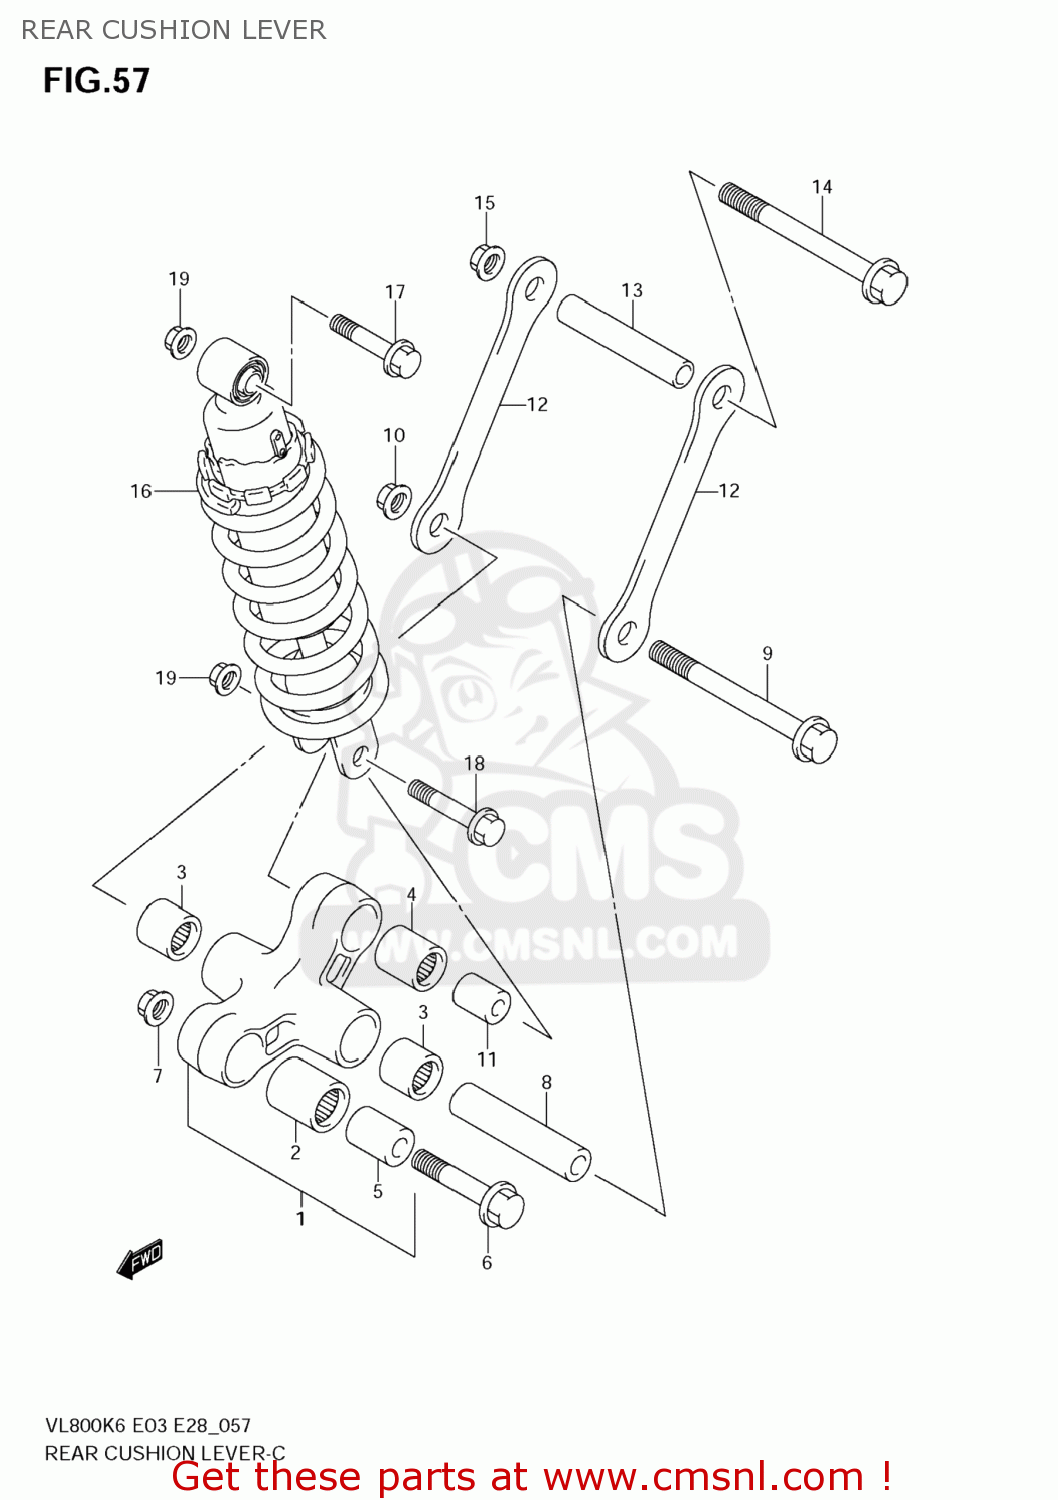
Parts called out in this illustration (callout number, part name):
1	LEVER SET,RR CUSHION
2	BEARING(20X27X30)
3	BEARING(17X24X20)
4	BEARING(17X24X26)
5	SPACER,RR CUSHION LEVER FR
6	BOLT,CUSHION LEVER FR
7	NUT
8	SPACER,RR CUSHION LEVER CTR
9	BOLT,RR CUSHION LEVER CTR
10	NUT
11	SPACER,RR CUSHION LEVER
12	ROD,RR CUSHION
13	SPACER,RR CUSHION LEVER CTR
14	BOLT,RR CUSHION LEVER CTR
15	NUT
16	ABSORBER ASSY,RR SHOCK
17	BOLT(10X50)
18	BOLT(10X54)
19	NUT
